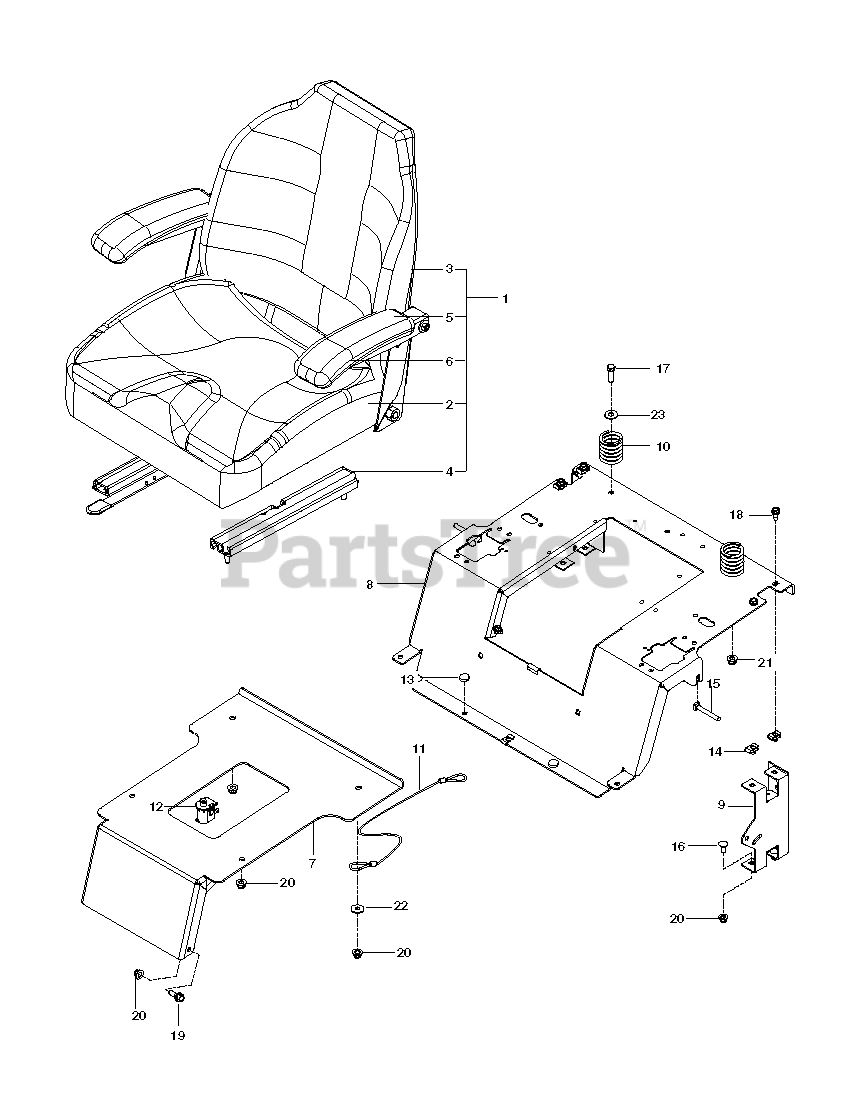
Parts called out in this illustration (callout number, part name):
4	4"SINGLE LOCK TRACK SET W/HDWR
5	BLACK SELFSKIN-ARM PAD ONLY
6	LEFT SELFSKINNED 907 ARM W/BRK
7	WLDMT, SEAT PAN, BLUE
11	SEAT LANYARD
12	SEAT SWITCH
13	GROMMET, BUMPER
14	U-CLIP 5/16-18 NUT RETAINER
15	RHSNB 5/16-18 X 2-1/2 GR5 ZD
16	BOLT 5/16C X 3/4" CARRIAGE
17	HCS 3/8C X 1 1/4 GR5
18	BOLT 5/16-18 X 3/4
19	SB 5/16-18 HEX HD GD5, BLK ZN
20	5/16-18 NYLOC FLANGE NUT
21	NUT 3/8-16 NYLOC
22	WASHER 5/16 FLAT
23	WASHER 3/8 SAE FLAT
